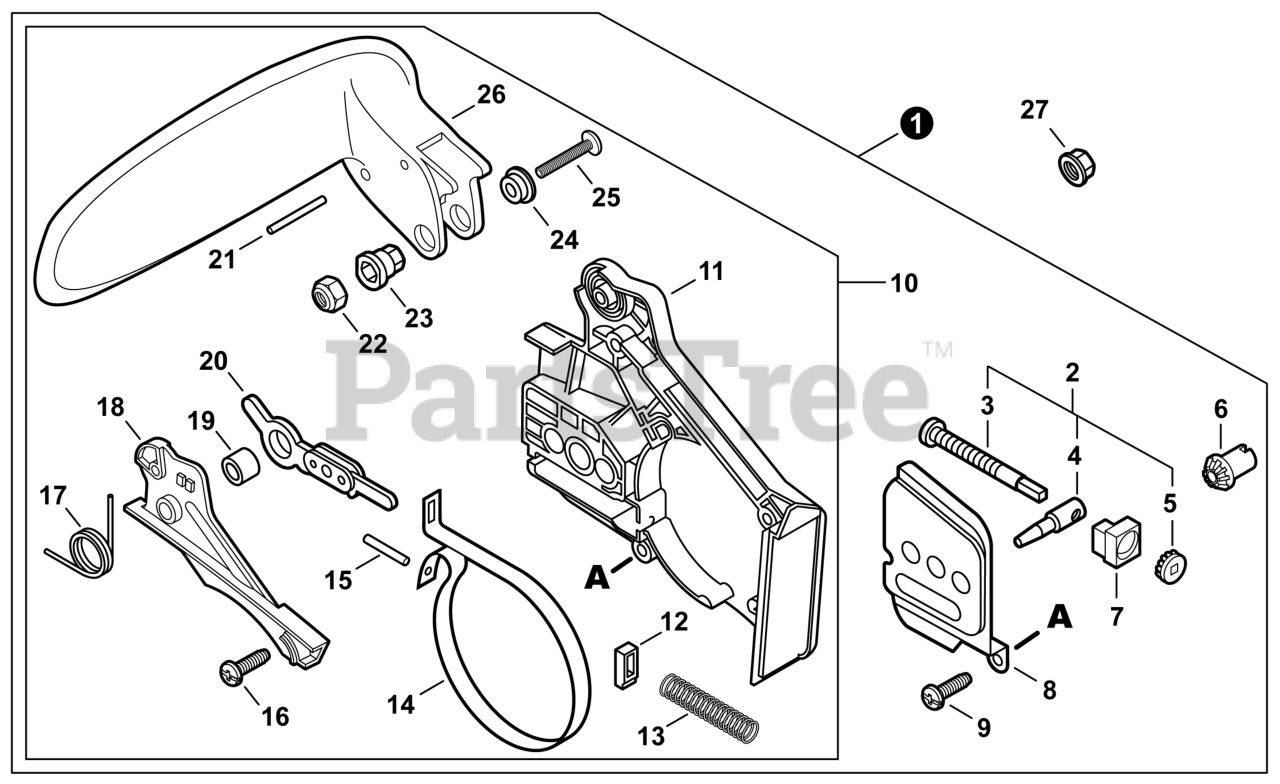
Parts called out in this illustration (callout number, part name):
1	BRAKE ASSY, CHAIN
2	TENSIONER SET, CHAIN
3	SCREW, CHAIN TENSION
4	TENSIONER, CHAIN
5	GEAR, BEVEL
6	GEAR, BEVEL
7	COLLAR 8
8	PLATE, GUIDE - OUTER
9	SCREW 4×12
10	BRAKE ASSY, CHAIN
11	GUARD, SPROCKET
13	SPRING, COMPRESSION
14	BAND, BRAKE
15	PIN, SPRING 3×9.8
16	SCREW 4×12
17	SPRING, TORSION
18	COVER, BRAKE
19	SPACER 8×12×9
20	CONNECTOR, BRAKE
21	PIN 3×26
22	NUT, LOCK M5
23	COLLAR 5
24	COLLAR 5.3×10×13×L5
25	SCREW 5×32
26	BRAKE, CHAIN
27	NUT, FLANGE M8×1.25
